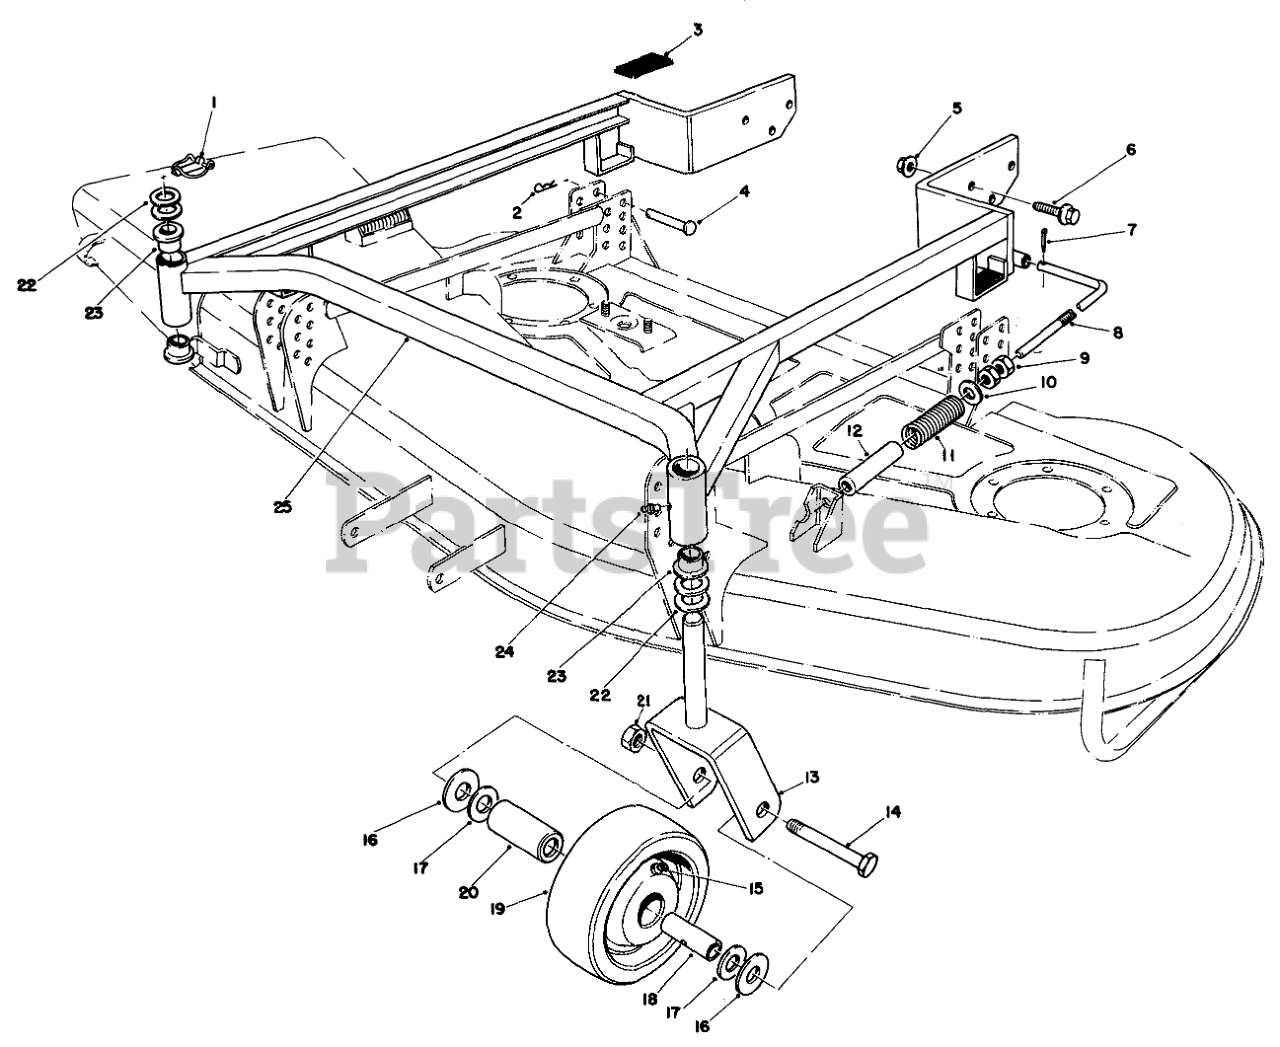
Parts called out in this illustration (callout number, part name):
1	PIN-LYNCH
2	PIN-HAIR
3	Cushion-Rubber
4	PIN-CLEVIS
5	NUT-LOCK, FLANGE
6	SCREW-HHF
7	PIN-COTTER
8	ADJUSTING SHAFT
9	NUT-JAM
10	WASHER
11	SPRING-COMPRESSION
12	SLEEVE-TUBE, 36 INCH
13	FORK-Castor
14	SCREW-HH
15	FITTING-GREASE
16	THRUST WASHER
17	BEARING RETAINER
18	SPANNER BUSHING
19	WHEEL
20	ROLLER BEARING
21	NUT-HEX
22	WASHER-THRUST
23	Bushing
24	FITTING-GREASE
25	Frame-Carrier (Incl. Ref. #23)
